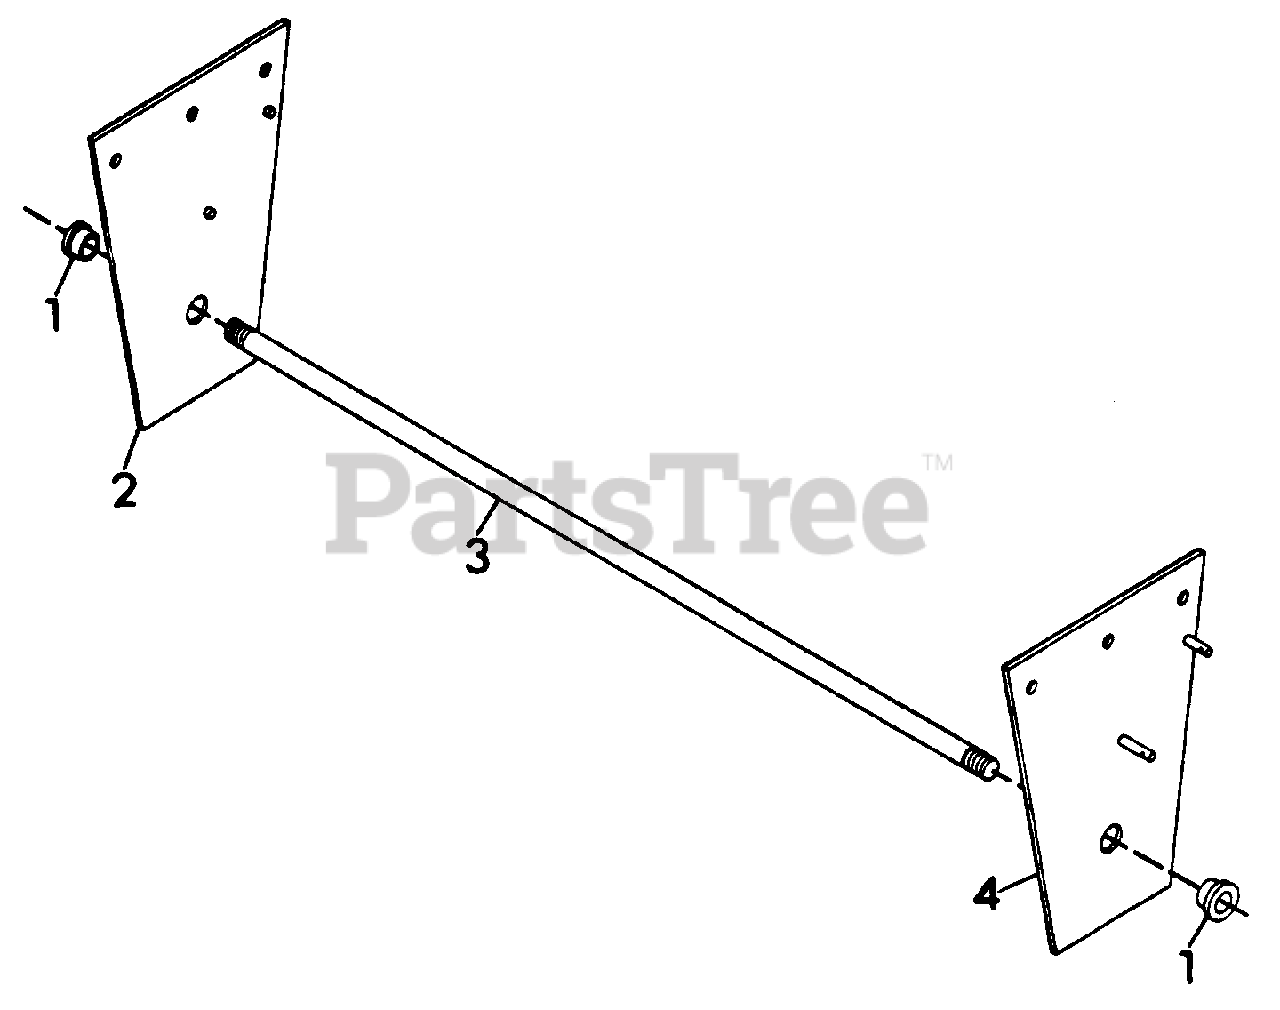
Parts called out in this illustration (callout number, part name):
1	BUSH.,F.890X1.50X.700 NY
2	WLDMT,AXLE PLATE L.H.
3	SHFT,AXLE
4	WLDMT,AXLE PLATE R.H.
